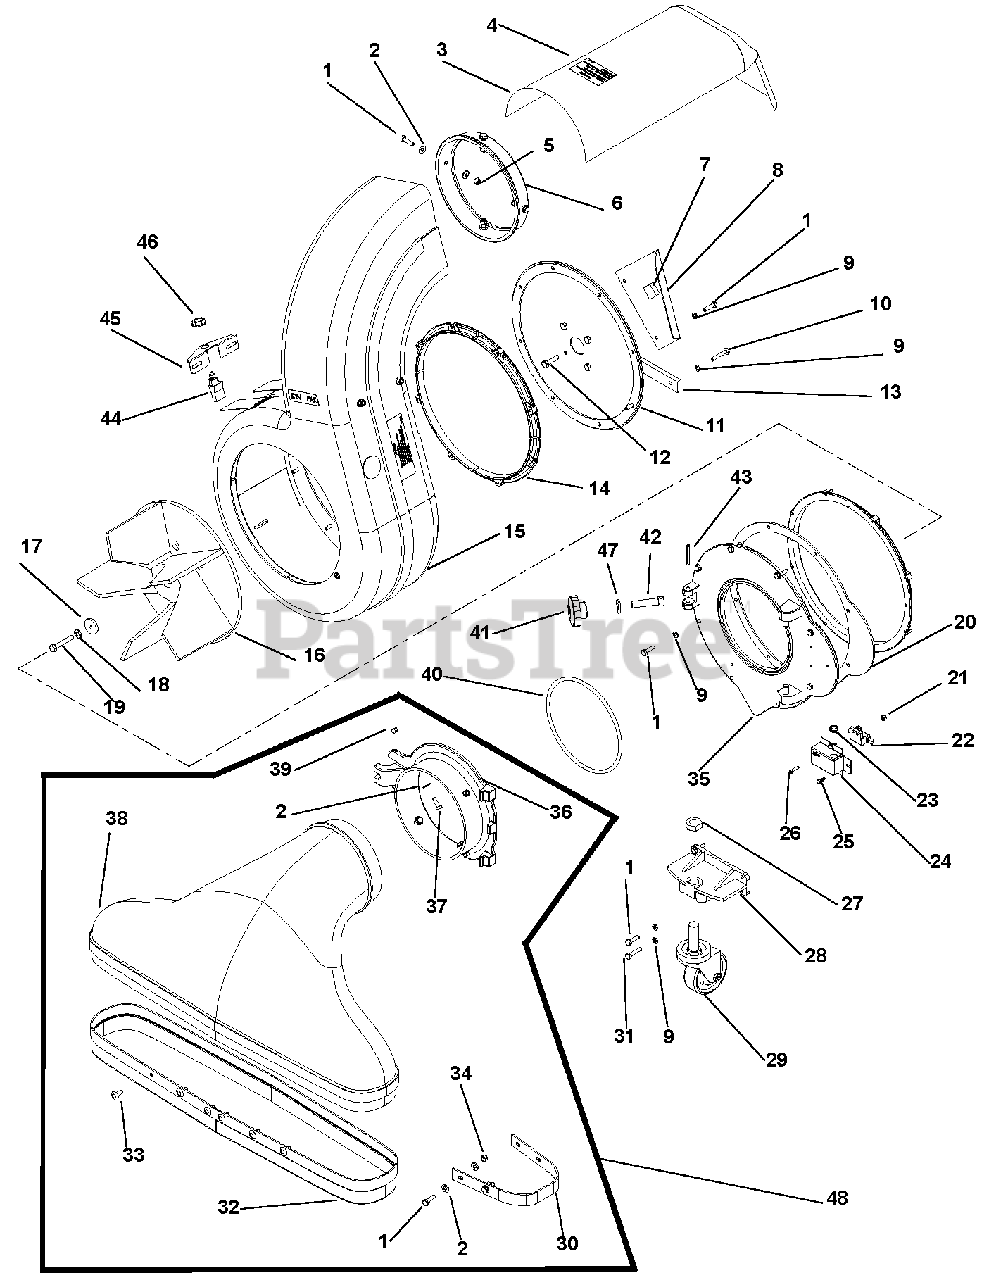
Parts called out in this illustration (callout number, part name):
1	Bolt, Hex .25-20 x 1.00
2	Washer, Flat Steel .281 x .62 x .065
3	Spin Pak Deflector
4	Decal, Danger Discharge
5	Nut, Locking Nylon .250-20
6	Retaining Ring
7	Anti Vibration Sponge
8	Heat Shield
9	Washer, Locking .25 x .062 Regular
10	Bolt, Hex .25-20 x 1.50 Grade 5
11	Back Cover and Gasket Assembly
12	Bolt, Hex .31-24 x 1.25 Grade 5
13	Shim Plate, Blower Housing
14	Anti-Wrap Segments
15	Housing, Blower VAC 35 (Red)
16	Fan, 3/4" Shaft
17	Washer, .344 x 1.25 x .179 Fend
18	Washer, M8 x M19 x M1 Bellville Lock
19	Bolt, Hex .31-24 x 2.00
20	Gasket, Front Cover
21	Nut, Locking, Nylon 8-32 with Insert
22	Switch, Delta 6400-51
23	Grommet, Rubber, 3/8 ID, 1/2
24	Switch Bracket
25	Screw, Tapping 10-4 x .50 Hex Washer Head Thread Rolling
26	Screw, Machine, 8-32 x .75 Hex Washer Head
27	Nut, Jam .75-16
28	Caster Mount
31	Bolt, Hex .25-20 x 1.25
32	Skirt 30" Intake
34	Nut, Locking Center .25-20
35	Front Cover Casting w/Decal
36	Collar CV
37	Bolt, Hex .25-20 x .75 Grade 5
38	Intake Housing 30"
39	Nut, Locking Center .25-20
40	O-Ring Gasket
41	Knob, Plastic
42	Pivot Bolt
43	Pin, Roll .250 x 1.00
44	SE Switch, Delta (705-10 Reverse D)
45	Switch Bracket for 7050-10 16 Ga
46	Switch Nut 9250
47	Washer, Flat Steel .531 x 1.06 x .095
48	30" Intake Assembly Vac-35 (Red, Includes Items 1, 2, 30-39)
